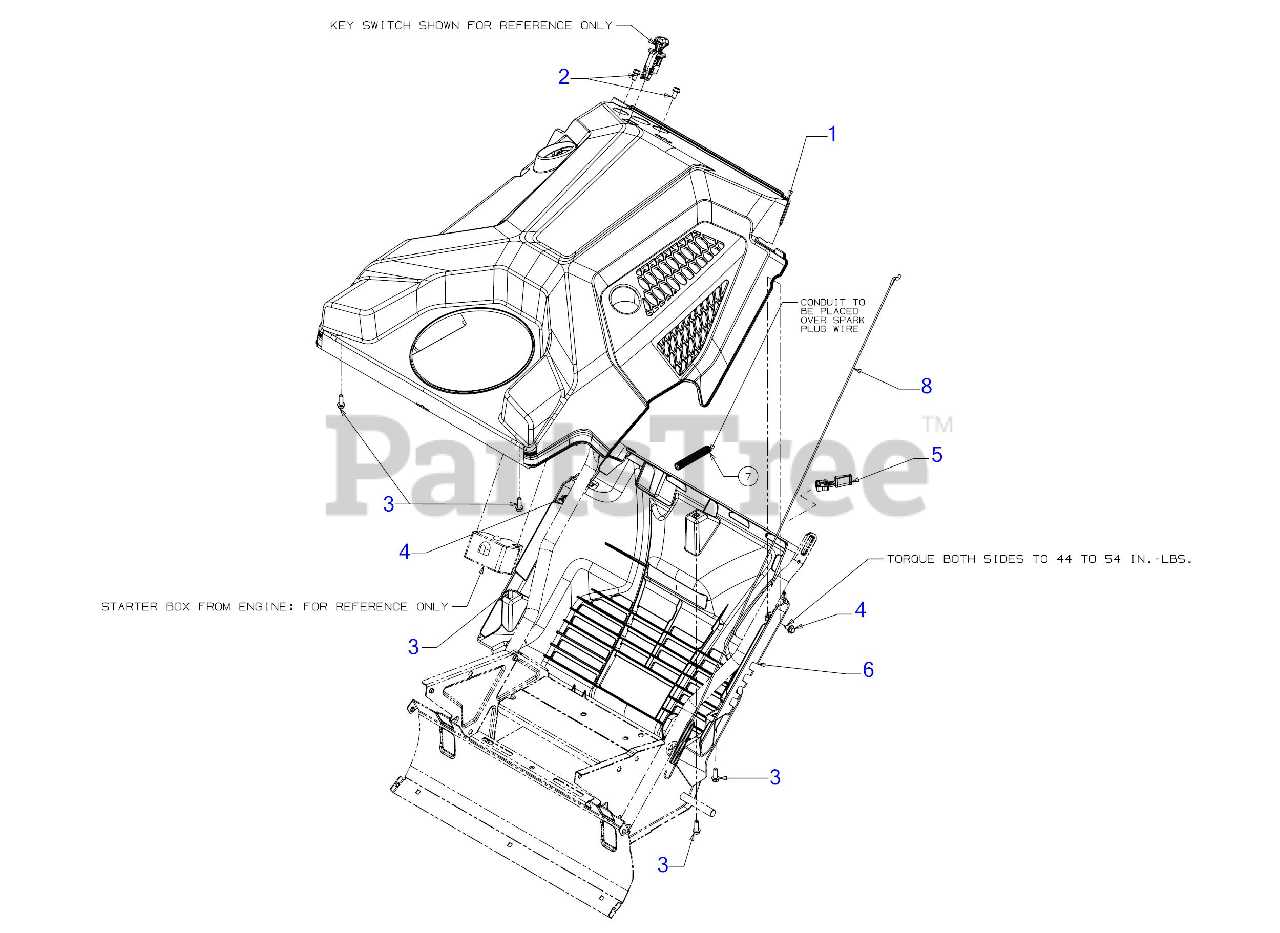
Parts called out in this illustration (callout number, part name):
1	COVER ASSEMBLY W/O LIGHT
2	HEX SCREW 1/4-15 x .50
3	SCREW 1/4-15 x .750
4	SCREW 1/4-20X.625
5	CHOKE EXTENION LEVER
6	BOTTOM COVER
7	CONVOLUTED CONDUIT
8	AUGER CLUTCH CABLE 37.05"
